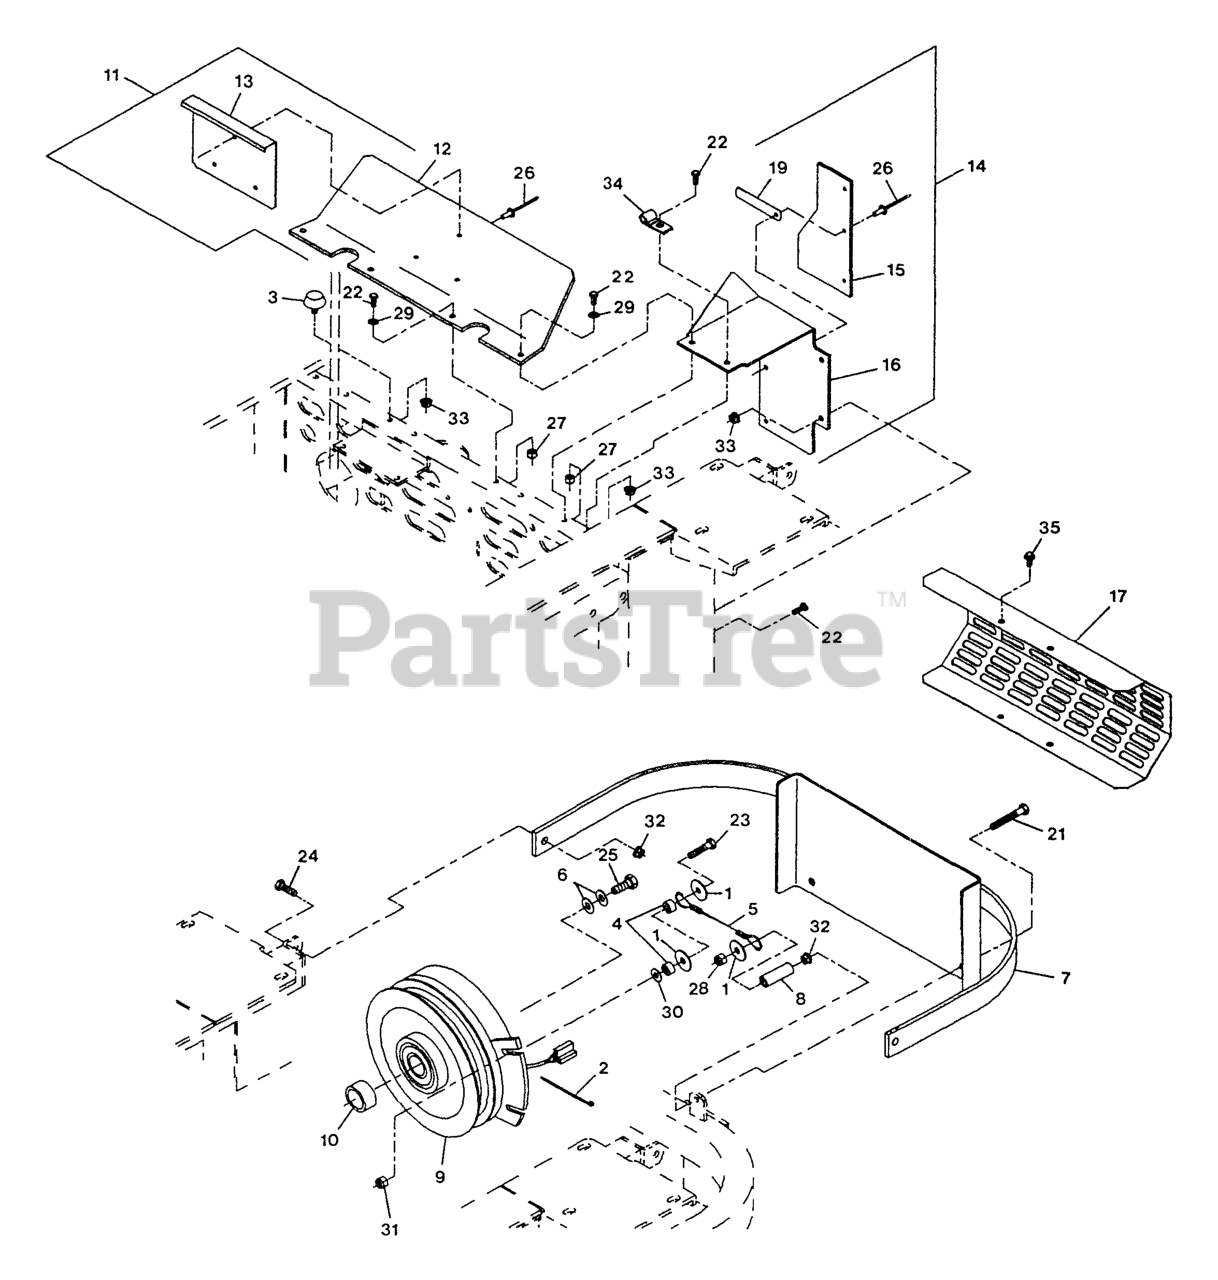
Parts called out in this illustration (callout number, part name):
2	TIE-PLASTIC
4	SPACER,CLUTCH ANCHOR
6	WASHER-SPRING
8	BUSHING-LEVER, LIFT
10	SPACER-CLUTCH
13	Shield, Lift
15	SHIELD-ENGINE
19	CLIP-BAFFLE, REAR
26	RIVET-POP
34	CLIP-LOOM
